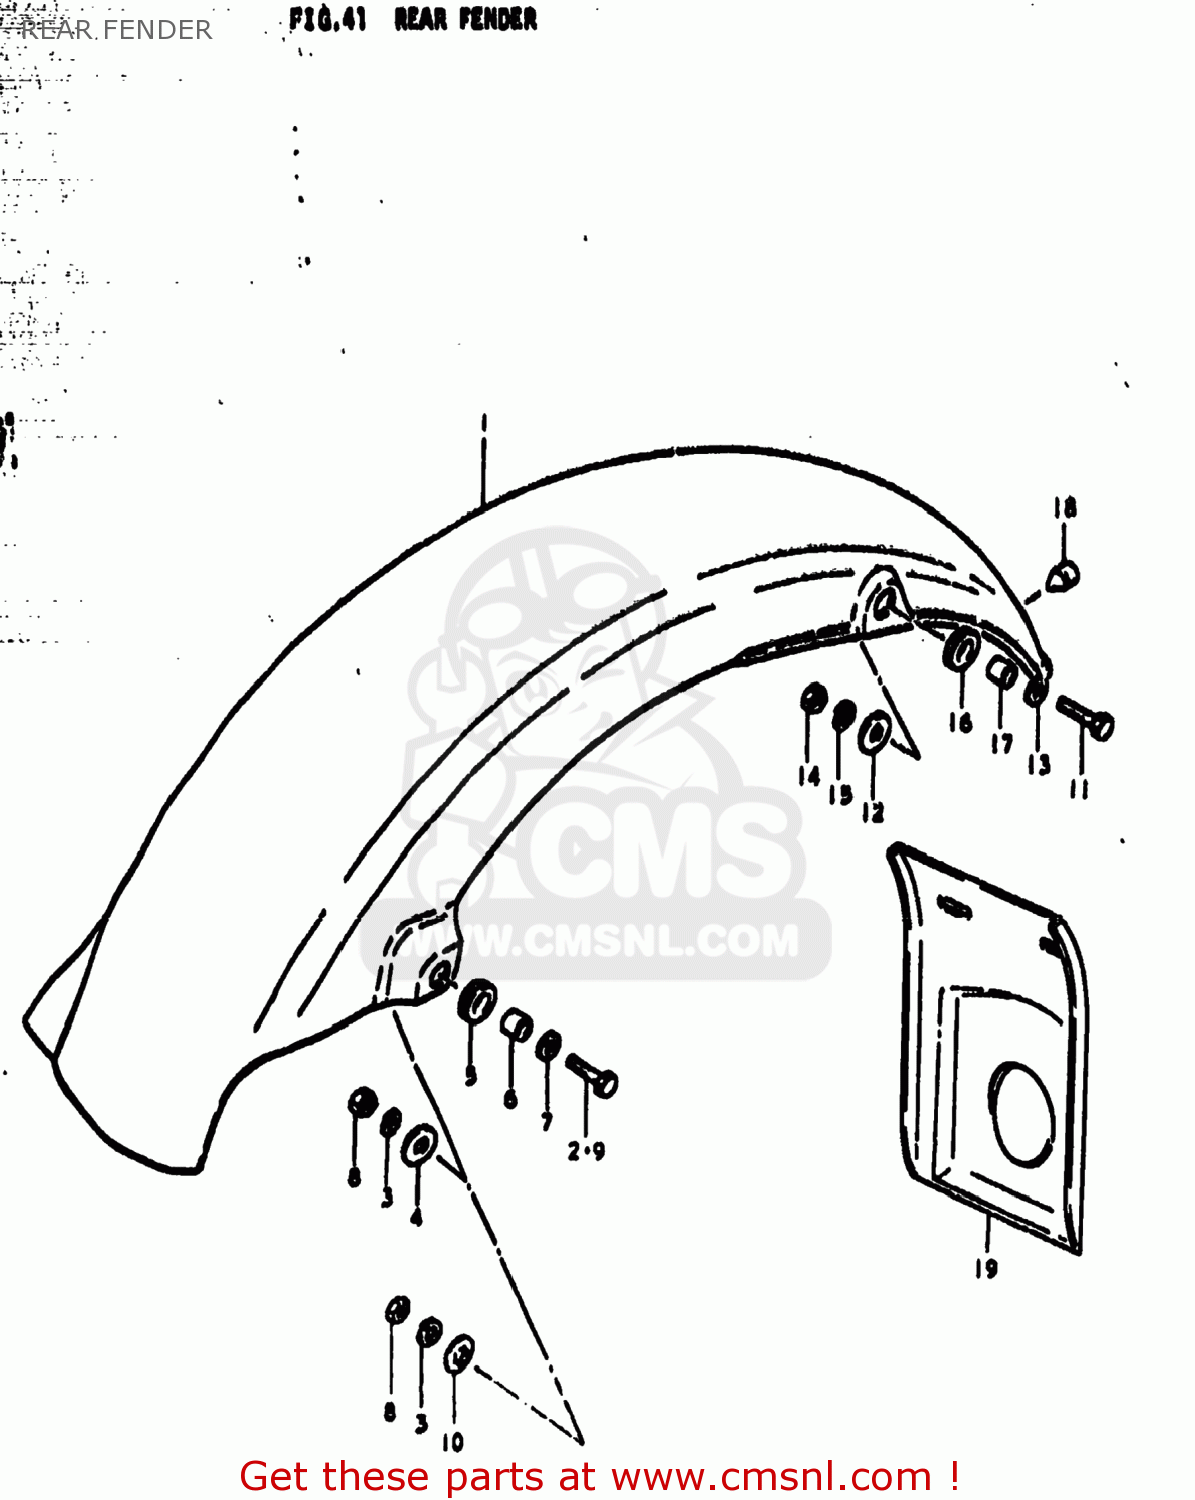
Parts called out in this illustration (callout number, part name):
1	FENDER,REAR
2	BOLT
3	LOCK WASHER
4	WASHER (6.5X20X1.2)
5	CUSHION
6	SPACER(6.1X9X7.5)
7	WASHER
8	NUT
9	BOLT
10	WASHER
11	BOLT (8X30)
12	WASHER(8.5X26X1.2)
13	WASHER
14	NUT
15	LOCK WASHER
16	CUSHION
17	SPACER (8.2X12X7.5)
18	CUSHION
19	MUD GUARD,REAR FENDER
